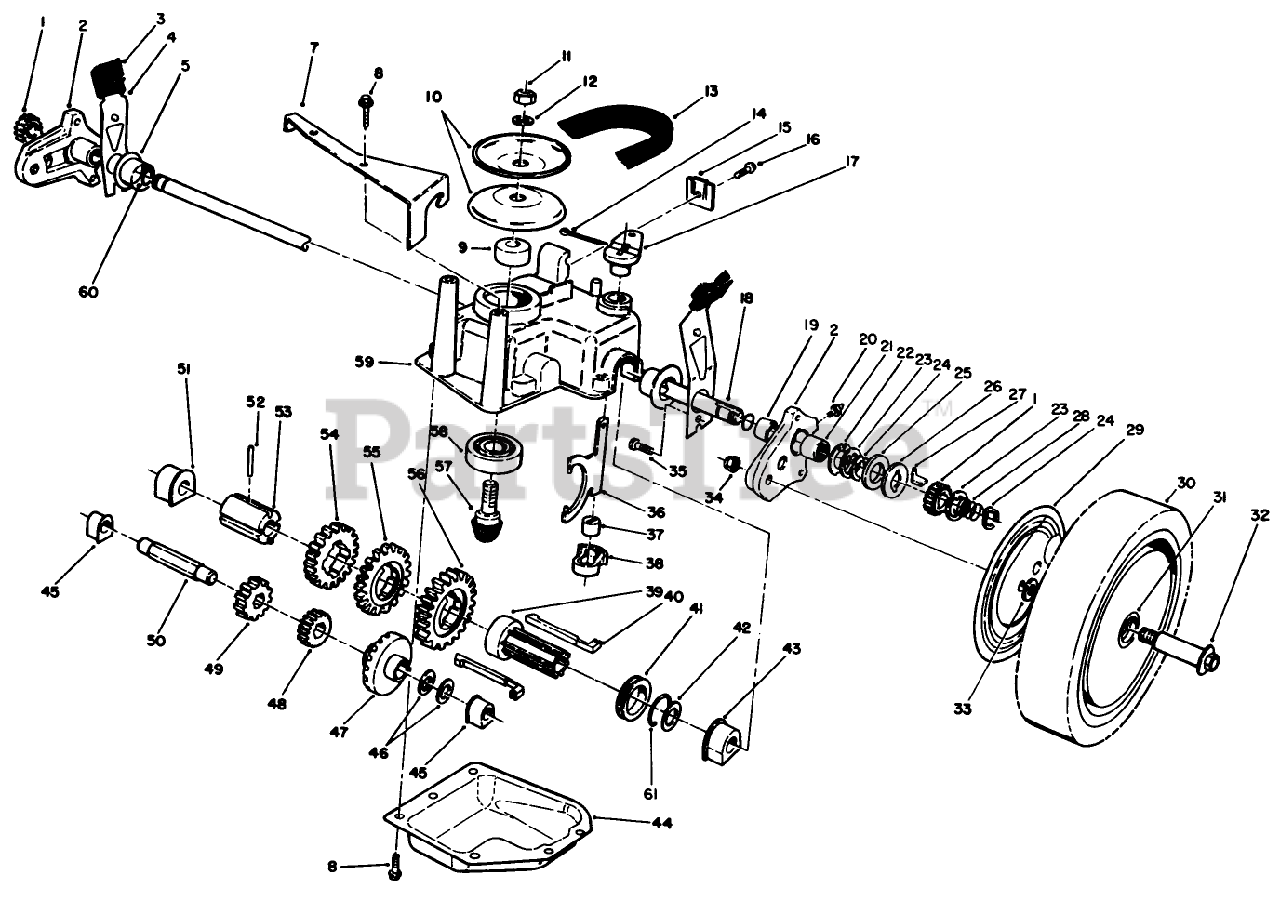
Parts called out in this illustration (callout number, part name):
1	GEAR-PINION
2	Pivot Arm Assembly (Incl. Ref. #19, 20, 21 )
3	KNOB-ARM
4	SPRING ARM ASM SP
5	CAP-END
7	Bracket-Belt Guide
8	SCREW-HWHTF
9	SPACER
10	Pulley Half
11	NUT-HEX
12	WASHER-FLAT
13	V-BELT E
14	PIN-COTTER
15	Cable Clamp
16	SCREW-HWHTF
17	SHIFT LEVER
18	Shaft-Output
19	BUSHING
20	FITTING-GREASE
21	BEARING-ROLLER
22	WASHER-ARM, PIVOT
23	Thrust Washer
24	RING-CLIP, LOCKING
25	Friction Ring
26	Pinion
27	KEY-ROCKING, LH
28	SPRING-COMPRESSION
29	Cover-Wheel
30	Wheel-Tire & Gear Assy. (Incl. Ref. #31)
31	HOC ADJUSTMENT ASM
32	WHEEL BOLT
33	WASHER
34	Nut
35	SCREW-HWH
36	YOKE-SHIFT
37	BUSHING-YOKE
38	RETAINER-FORK, SHIFT
39	SHIFT KEY SLEEVE
40	SHIFT KEY
41	SHIFT COLLAR
42	Washer
43	BUSHING-OUTPUT
44	Cover-Gearcase
45	BUSHING
46	WASHER-THRUST
47	Gear-Bevel
48	PINION-20T
49	PINION-25T
50	SHAFT-INTERMEDIATE
51	BUSHING
52	PIN-SPRING
53	SLEEVE-GEAR
54	GEAR-39T
55	GEAR-44T
56	GEAR-49T
57	Gear-Pinion
58	BEARING-BALL
59	CASE-GEAR, UPPER
60	O-RING
61	CLIP-SPRING
